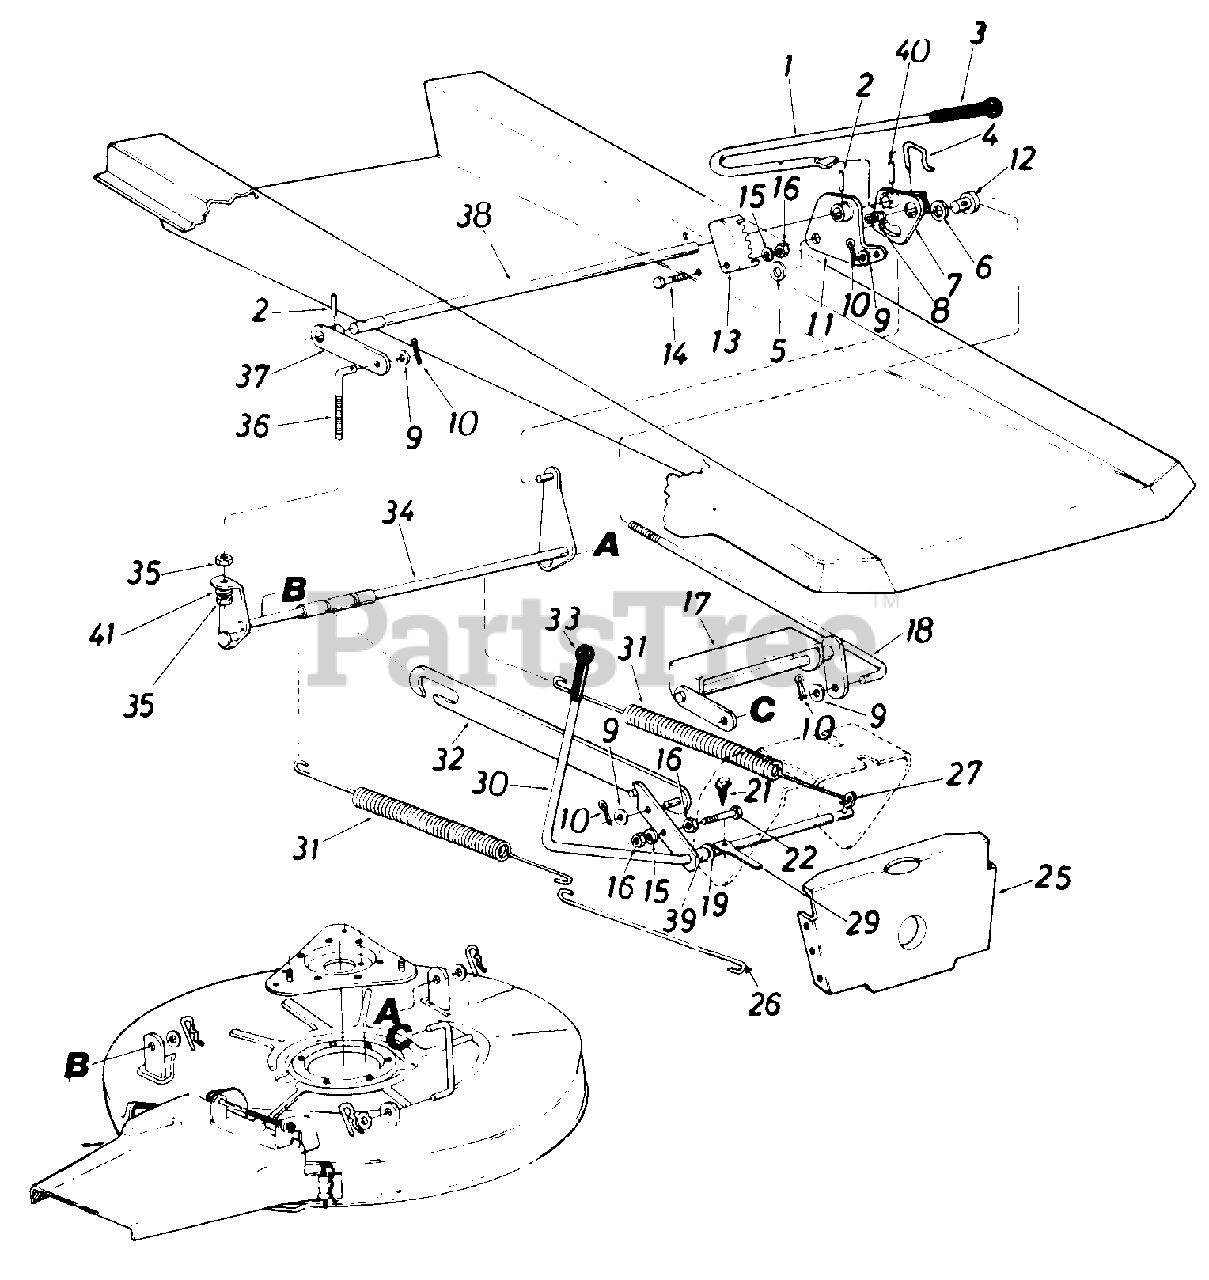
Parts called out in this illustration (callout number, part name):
1	Deck Lift Handle
2	Spring Pin Spir. 1/4" Dia. x 1.50" Lg.
4	Cotter Pin
5	Fl-Wash. 5/8" I.D. x 1.0" O.D. x .12
6	Fl-Wash. 5/8" I.D. x 1.25" O.D. x .60
7	Deck Lift Handle Brk't. Ass 'y.
8	Compression Spring .50' O.D. x 1.04
9	Fl-Wash. .385" I.D. x .87" O.D. x .06
10	Cotter Pin 1/8" Dia. x 1.00"
11	Deck Lift Brk't. Ass'y. L.H.
12	Adj. Ferrule Deck Lift Handle
13	Index Bracket
14	Hex Bolt 5/16-18 x .75" Lg.
15	L-Wash. 5/16" I.D.
16	Hex Nut 5/16-18 Thd.
17	Deck Lift Ass'y. Front
18	Deck Lift Connecting Rod
19	Fl-Wash. .531" I.D. x .930"
21	Hex Wash. Hd. Self-Tap Scr. 1/4-20 x .50" Lg.
22	Hex Bolt 5/16-18 x 1.50" Lg.
25	Pivot Bar Bracket
26	Spring Hook
27	Spec. Clevis Pin .250" Dia.
29	Switch Actuator
30	Blade Engagement Lever Ass'y.
31	Extension Spring .99" O.D. x 14.25" Lg.
32	Deck Drive Control Brk't. Ass'y.
34	Deck Link Ass'y. Rear
35	Hex Nut 3/8-16 Thd.
36	Deck Adj. Scr. 3/8-16 Thd.
37	Deck Lift Brk't. Ass'y. R.H.
38	Rear Height Adj. Shaft
39	Sleeve .511" I.D. x .70" O.D. x .37" Lg.
40	Spring Pin Spir. 3116" Dia. x 1.50" Lg.
41	L-Wash. 3/8 I.D.
